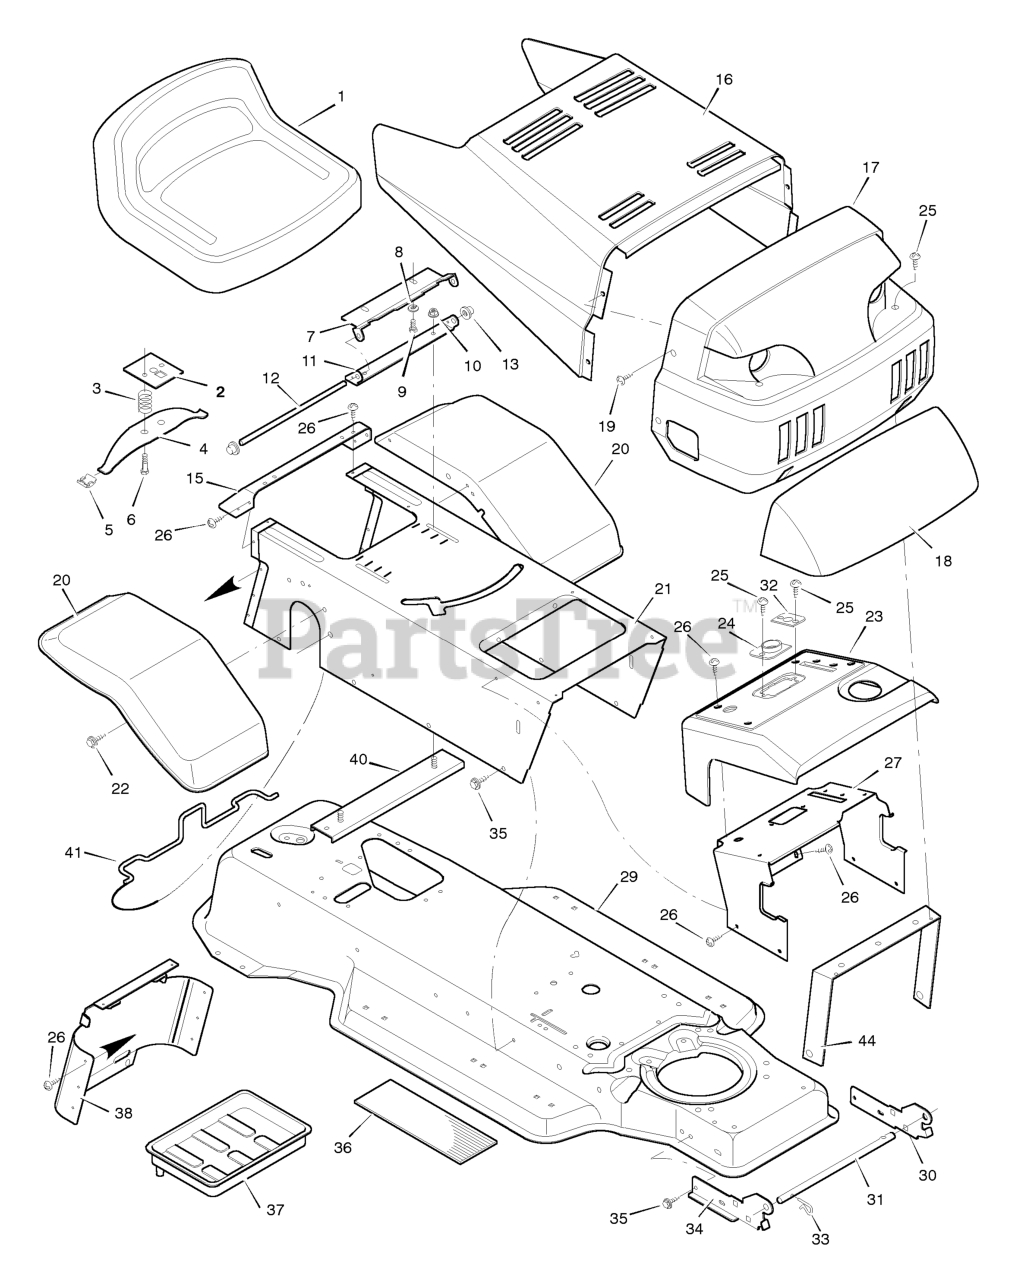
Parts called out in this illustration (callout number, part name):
2	Plate Assembly, Switch
3	Spring, Compression
4	Spring, Seat
5	Glide, Spring
6	Bolt, Shoulder
7	Support, Seat
8	Lockwasher
9	Bolt, Hex
10	Locknut, Flange
11	Bracket, Pivot
12	Rod, Pivot
13	Cap, Push On
15	Fender, Apron
17	Grille Assembly
21	Console Assembly
23	Dash Panel
24	Bearing, Steering
26	Screw
27	Support, Dash
29	Frame Assembly
30	Bracket, Left Grille
31	Rod, Pivot
32	Bearing
33	Pin, Hair
34	Bracket, Right Grille
37	Tray, Battery
38	Cap, Console
39	Bolt
40	Channel Assembly
41	Clamp, Battery
44	Brace, Grille
